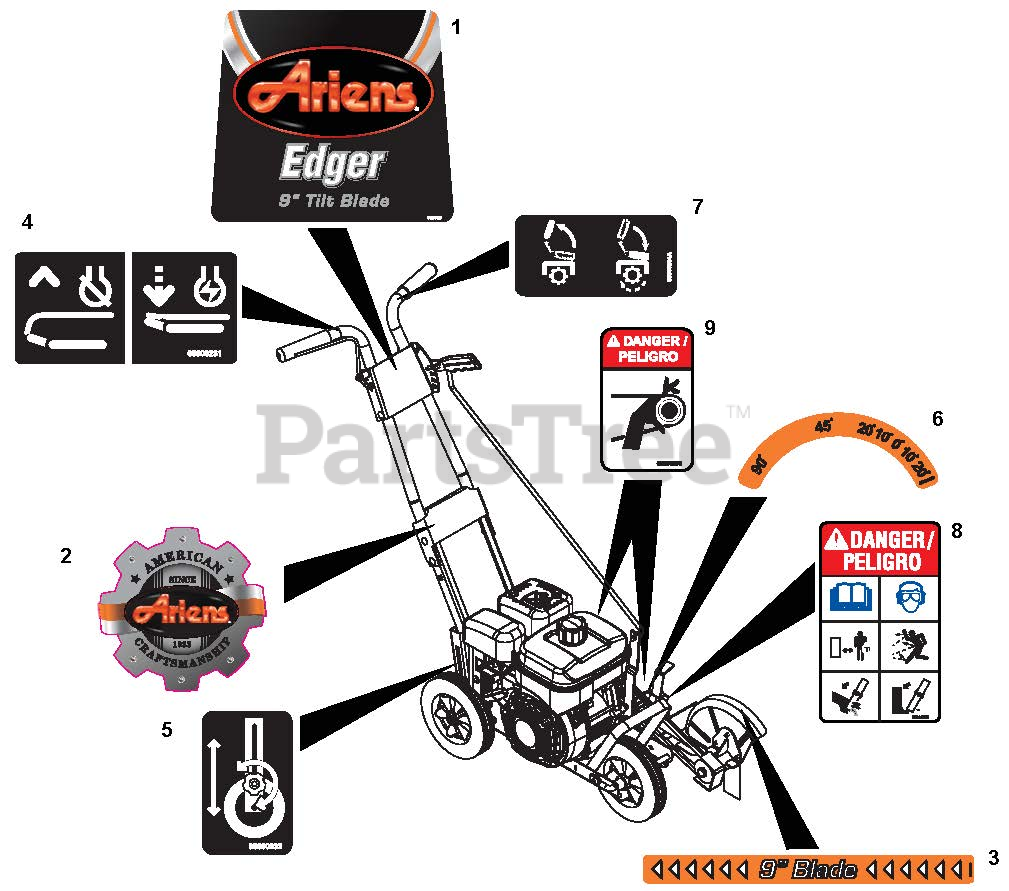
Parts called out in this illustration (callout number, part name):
1	DECAL, EDGER-ARIENS
2	Decal, Ariens Heritage-Small
3	DECAL, EDGER BLADE
4	DECAL, EDGER OPC
5	DECAL, EDGER DROP WHEEL
6	DECAL, EDGER BLADE TIP
7	DECAL, EDGER DEPTH CONTROL
8	DECAL, EDGER WARNING
9	DECAL, EDGER BELT FINGER
